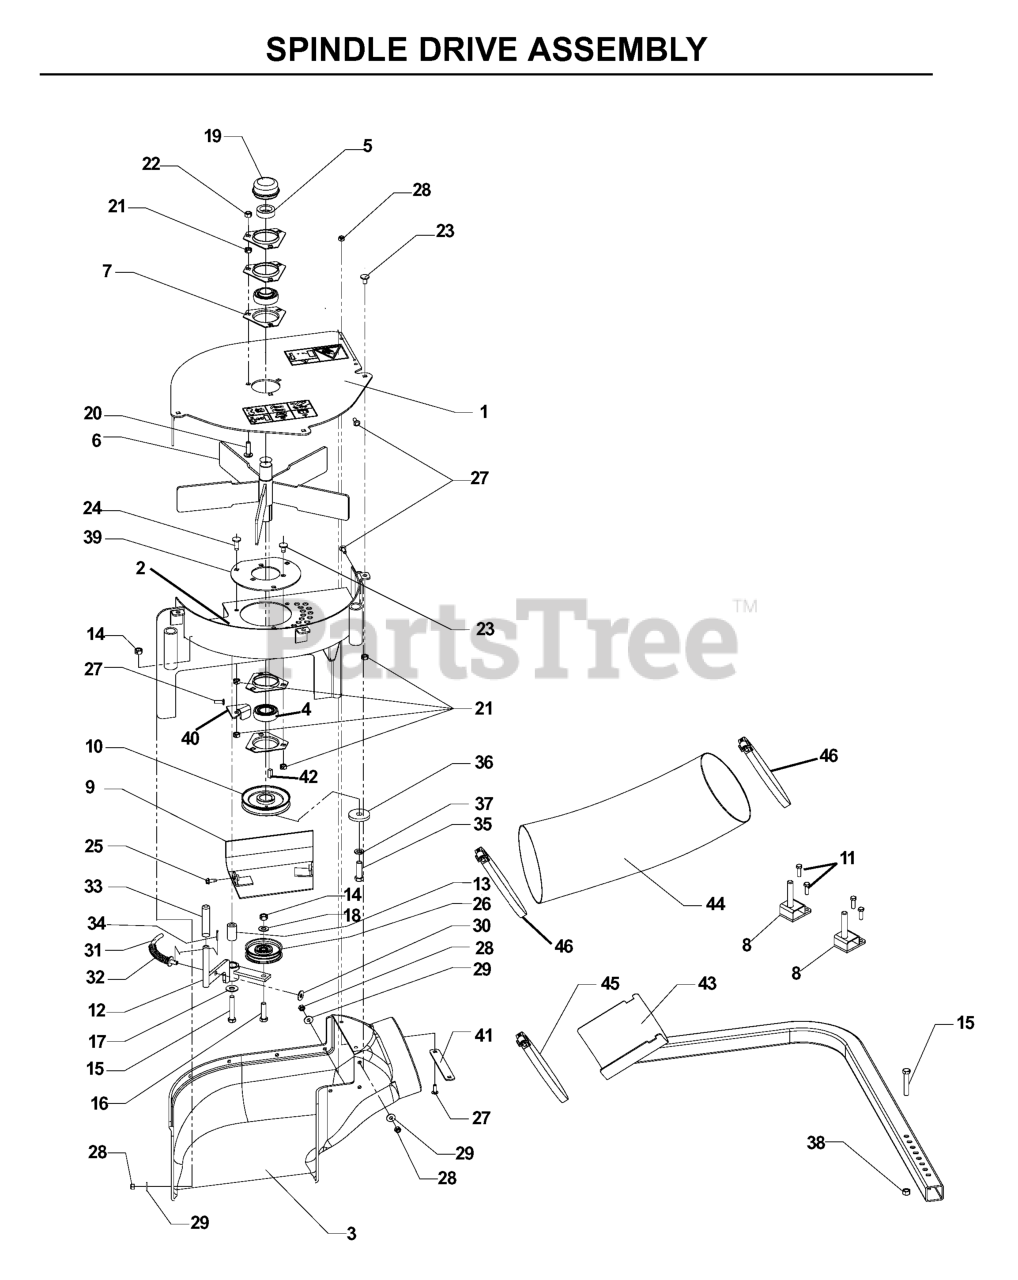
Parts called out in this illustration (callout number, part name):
1	FAN COVER W/DECALS
2	BLOWER HOUSING WELDMENT
3	LOWER HOUSING
4	BEARING KIT-2 PCS
5	BEARING KIT-2 PCS
6	FAN
7	BRG FLANGE
8	BLOWER PIN WELDMENT ASM.
9	COVER PLATE WELDMENT
11	HCS 3/8C X 1 1/4 GR5
13	BUSHING, SLEEVE
14	NUT 3/8C CENTERBLOCK
15	HCS 3/8C X 2 1/4
16	HCS 3/8C X 1 1/2
17	WASHER 3/8 FLAT
18	WASHER 3/8 SAE FLAT
19	GREASE CAP
20	BOLT, CARRIAGE 5/16X1-1/4
21	NUT 5/16C CENTERLOCK
22	NUT 5/16 NYLOC
23	CARRIAGE BOLT 5/16C X 5/8"
24	RHSNB 5/16C X 1
25	SCREW 1/4 X 5/8
27	RHSNB 1/4C X 3/4
28	NUT.1/4-20.HEX.NYLOC.ZD
29	WASHER 1/4 FLAT
30	FLAT WASHER 5/16 SAE
31	SPRING ROD WLDMNT
34	COTTER PIN 3/32 X 3/4
35	HCS 7/16F X 1 1/2
36	SPINDLE WASHER
37	WASHER 7/16 LOCK
38	NUT 3/8-16 NYLOC
39	BEARING PLATE - BLACK
40	BELT GUIDE
41	BACKING (BLACK)
42	KEY 1/4 SQ X 3/4
43	SUPPORT WELDMENT
44	HOSE 7 X 82 CLEAR
45	HOSE CLAMP 4-1/8 TO 7"
46	OVER CTR BAND
